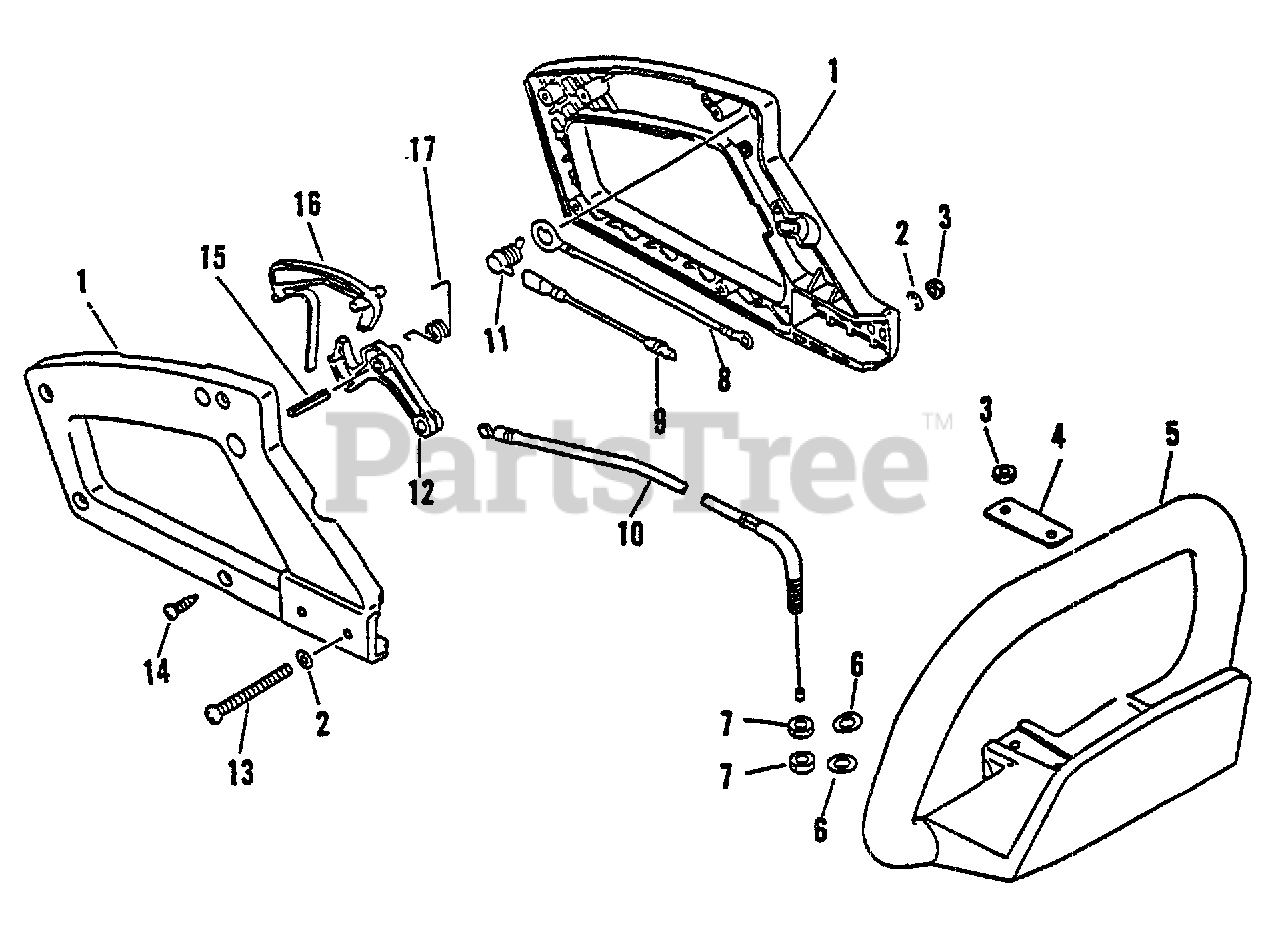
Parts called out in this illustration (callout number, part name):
1	HANDLE ASSY - REAR
2	WASHER - 5
3	LOCKNUT - 5
5	HANDLE - FRONT
6	WASHER - 6
8	LEAD - GROUND
9	LEAD - GROUND
10	CABLE, THROTTLE
11	IGNITION SWITCH ASSY
12	TRIGGER, THROTTLE
13	SCREW - 5X55
14	SCREW - 4X16
15	PIN - SPRING -- 5X25
16	LOCKOUT, THROTTLE
17	SPRING, TRIGGER
